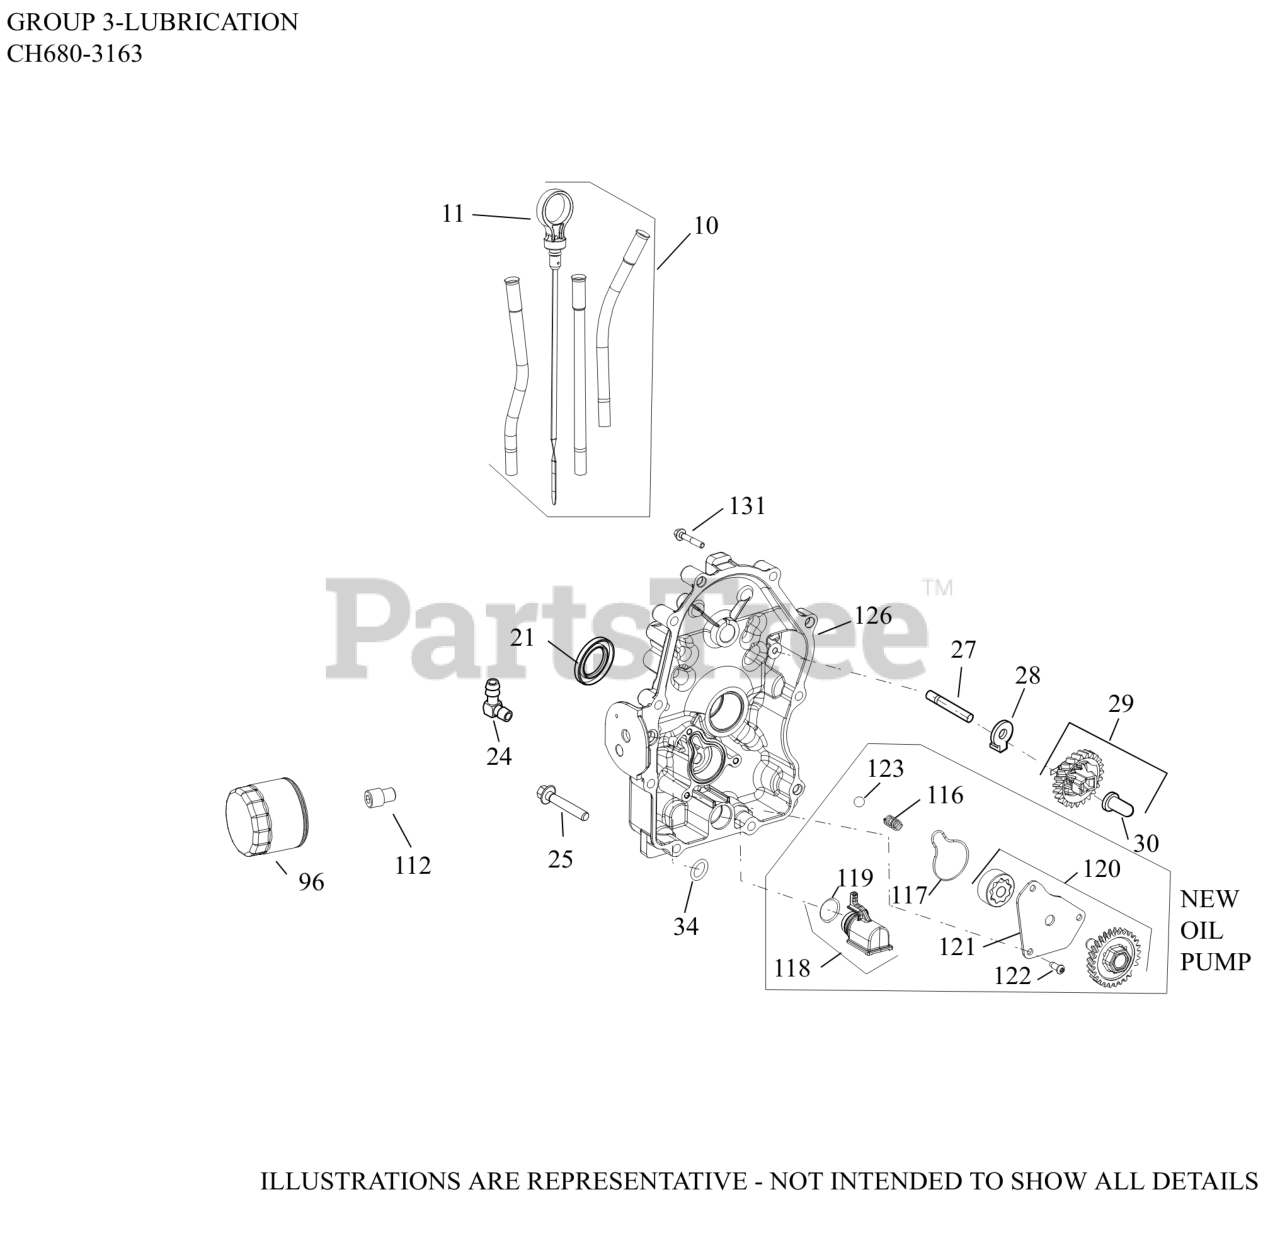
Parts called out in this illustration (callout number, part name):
10	KIT, DIPSTICK/DIPSTICK TUBES
24	CONNECTOR, 90 DEG. HOSE
25	SCREW, FLG M8X1.25X45
27	SHAFT, GOVERNOR GEAR
28	TAB, LOCKING
29	KIT, GOVERNOR GEAR W/PIN
30	PIN, GOVERNOR REGULATING
96	OIL FILTER
96	FILTER, OIL EXTENDED LIFE
112	NIPPLE, OIL FILTER
116	SPRING, COMPRESSION
117	SEAL, OIL PUMP COVER
118	PICK-UP ASSEMBLY, OIL
119	O-RING, OIL PICK-UP
120	PUMP ASSEMBLY, OIL
121	COVER, OIL PUMP
122	SCREW, BUTTON HEAD
123	PRESSURE RELIEF BALL
126	CLOSURE PLATE ASSEMBLY (SERVICE)
131	SCREW, HEX FLANGE
